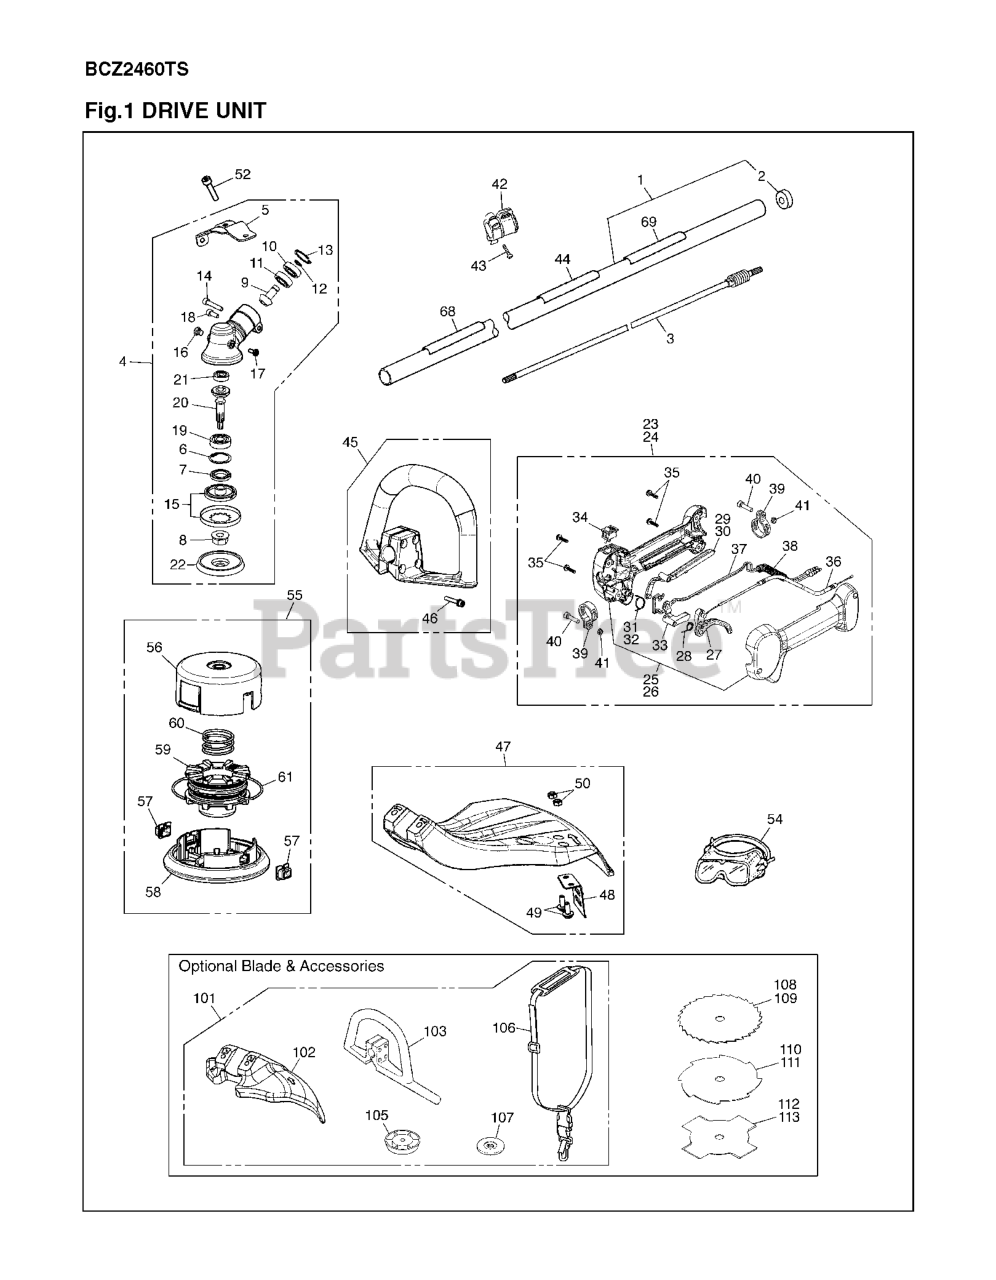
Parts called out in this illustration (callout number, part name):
1	PIPE COMP
3	DRIVESHAFT
4	BEVEL GEAR, KIT
8	GEARHEAD NUT - BRUSHCUTTER
14	BOLT M5X20 T27
15	DRIVER ASSY
16	SCREW M10X1.25 T27
18	BOLT (RPLS T495051010-11)
19	BEARING***
20	GEAR ASSY
21	BEARING (RPLS T330013520)
23	GRIP ASSY
24	GRIP ASSY
25	GRIP HALF SET
26	GRIP HALF SET
27	LEVER, THROTTLE
28	SPRING, THROTTLE
29	LEVER FOR GRIP (RPLS -0600)
30	LEVER, SAFETY
31	SPRING JOINT
32	SPRING
33	LEVER JOINT
37	CORD - C
41	NUT
42	HANGER COMP.
44	LABEL CAUTON FOR BC
45	HANDLE ASSY. (RPLS T319514001)
47	GUARD ASSY
52	BOLT, TORX
54	GOGGLExxx (RPLS
55	4" TAP TRIMMER HEAD PT104
56	CASE (RPL T318915112)
58	COVER (RPLS T318915131)
59	HOLDER, CORD (RPLS T318915141)
61	CORD
69	NAME PLATE BCZ260TS
101	BLADE KIT
103	HANDLE-ASSY
105	SUPPORTING CUP
106	STRAP ASSY
107	SUPPORT FLANGE
108	Brushcutter Blade, 22 Tooth 9"
109	Brushcutter Blade, 24 Tooth 9"
110	BLADE, 8
111	Brushcutter Blade, 8 Tooth 9"
112	BLADE, 8
113	Brushcutter Blade, 4 Tooth 9"
